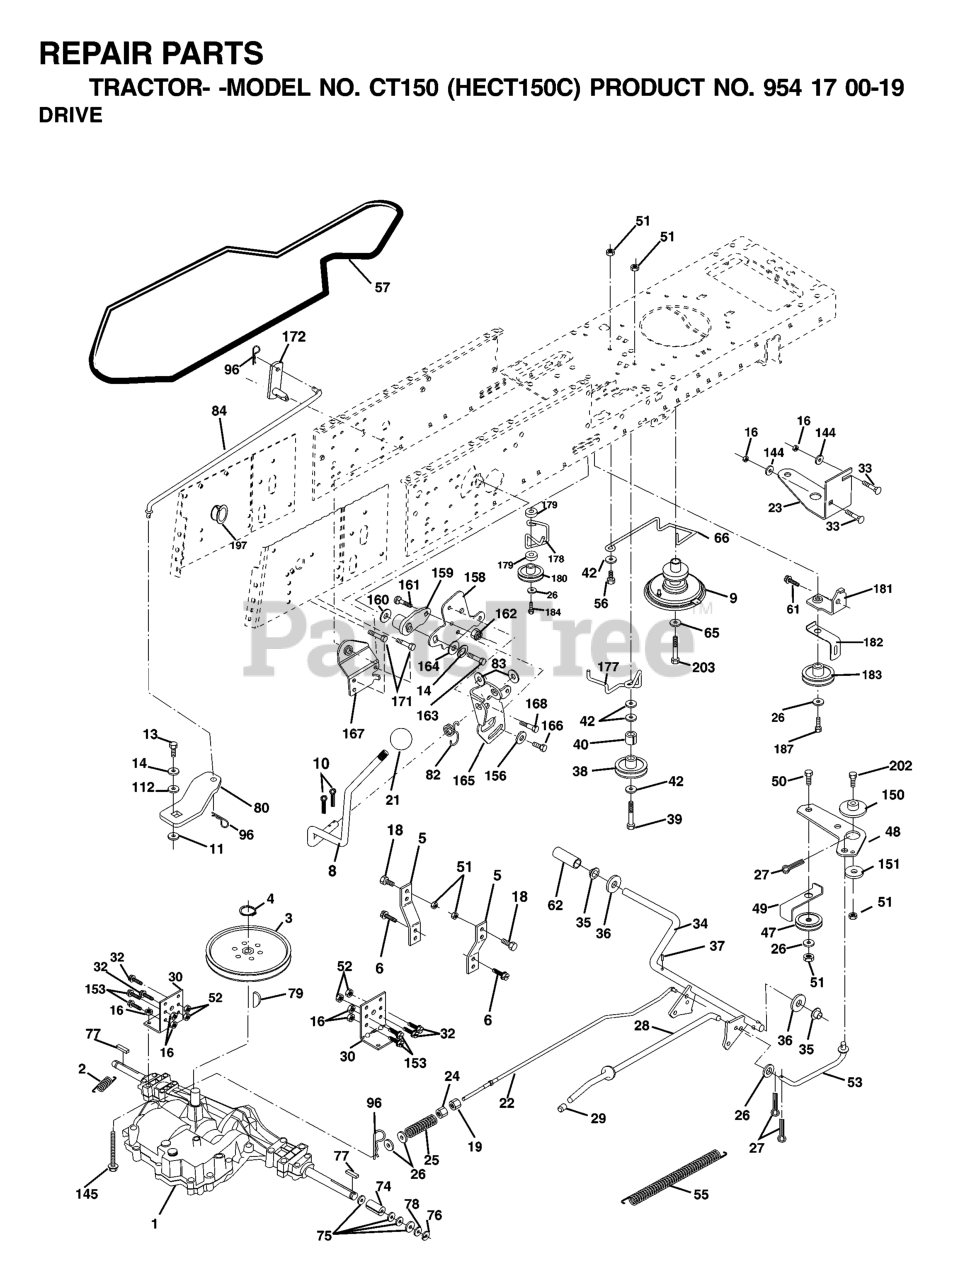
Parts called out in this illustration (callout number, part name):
2	SPRING,BRAKE RETURN
3	PULLEY
4	RETAINING RING LT
5	STRAP TORQUE
6	SCREW 5/16"
8	ROD.SHIFT.FENDER.ADJ.LT.CRD
9	CLUTCH ASSY
10	PIN COTTER
11	WASH-SHFT PLT LT
13	BOLT 1/4-28X3/4
14	LOCKWASHER
16	NUT.71038.31-18.HEX.NYLOCK
19	NUT
21	KNOB.DUCKHEAD.1/2
23	Bracket Clutch Noram
24	NUT
25	SPRING ROD LT
26	WASHER
27	COTTER PIN
28	ROD BRAKE PARK LT
29	PLUNGER CAP
30	BRKT, MOUNT TRNSAXLE
32	BOLT
33	Bolt Rdhd Sqnk 5/16-18 Unc x 3/4
35	BEARING.NYLON
37	DRIVE PIN
38	PULLEY.FLAT
42	WASHER
47	IDLER PULLEY
48	BELLCRANK, CLUTCH
49	RETAIN BELT
50	BOLT
52	LOCKNUT
53	LINK, CLUTCH LT
55	SPRING, RETURN LT
57	V-BELT.KEV.111"
61	SCREW 3/8-16X3/4
62	COVER, PEDAL (1 2)
65	LOCKWASHER
66	KEEPER BELT ENGINE
74	SPACER AXLE
77	SQUARE KEY
79	KEY STD (1373) DANA
82	SPRING,TORSION
83	WASHER
96	RETAINER M
144	Washer 11/32 x 5/8 x 16 Ga SD
150	BUSHING.BELLCRANK.GRD.DR
151	WASHER 12/32X2X10GA
153	BOLT RB
156	WASHER.SRRTD.5/16
158	BRACKET
159	HUB
160	Washer 29/32 x 1 - 1/4 x 16 Ga.
161	BOLT
162	NUT.CROWNLOCK.1/4
164	Washer 5/8 x .281 x 10 Ga.
165	RP BRACKET
167	BRACKET.SUPT.SHIFT.CRD
168	BOLT.SHOULDER.5/16-18X
172	SHAFT
180	PULLEY.FLAT.IDLER
181	BRKT.IDLER.GRD.DR.CRD
182	KEEPER BELT
183	PULLEY.V-IDLER
184	SCREW.HXWSH.3/8
187	SCREW
197	NYLINER SNAP 5/8" ID
202	BOLT.3/8-16X1.50
203	BOLT.HEX.7/16-20 X 5
